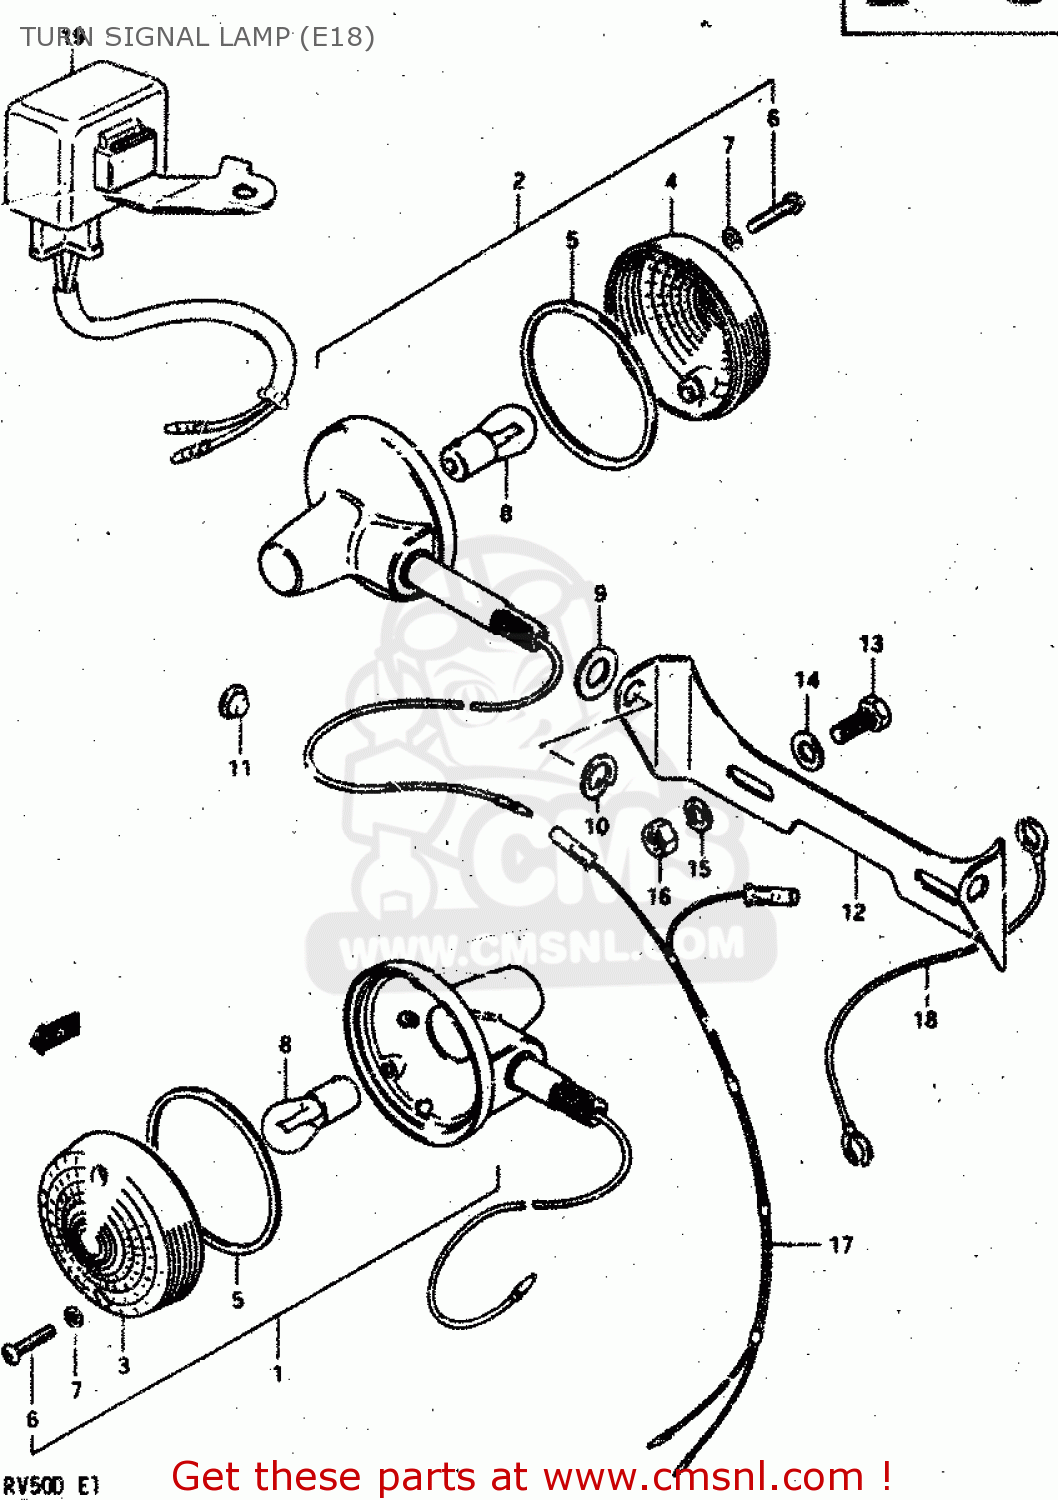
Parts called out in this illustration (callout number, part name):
1	LAMP, FRONT TURN SIGNAL
2	LAMP, REAR TURN SIGNAL
3	LENS
4	LENS
5	GASKET (NAS)
6	SCREW
7	GASKET (NAS)
8	BULB (6V,21W)
9	WASHER
10	LOCK WASHER
11	CAP(OD:10)
12	BRACKET, REAR TURN SIGNAL
13	BOLT, UPPER
14	WASHER(6.5X16X1.2)
15	LOCK WASHER
16	NUT
17	LEAD WIRE, REAR TURN SIGNAL
18	WIRE
19	RELAY, TURN SIGNAL
